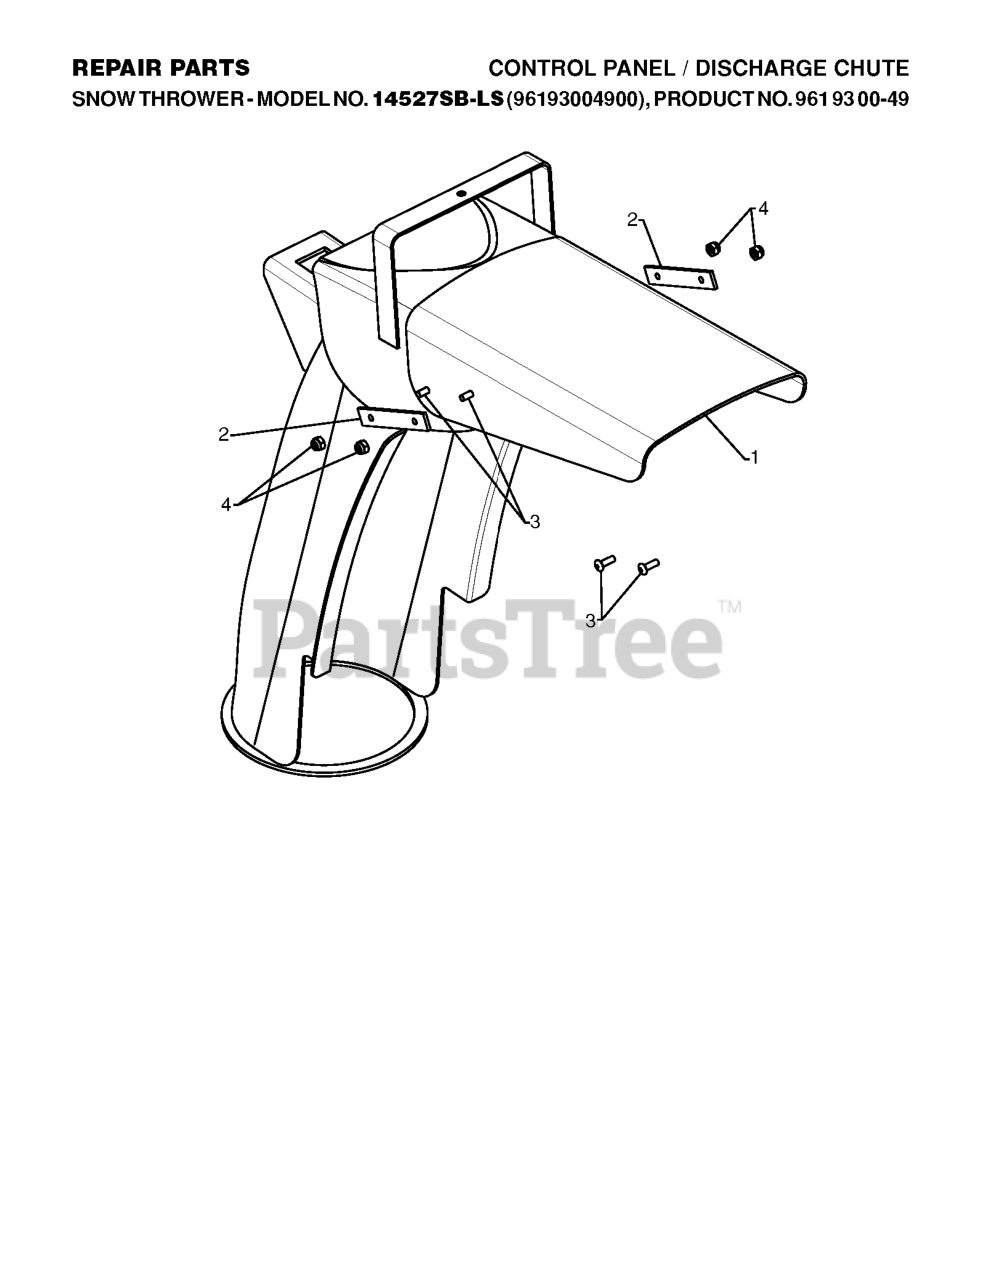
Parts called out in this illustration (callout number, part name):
1	SHIELD.DEFLECTOR.BLACK.SNOW
2	DEFLECTOR SHIELD STRAP
3	SCREW.#8.MACH
4	NUT.HEX.#8
